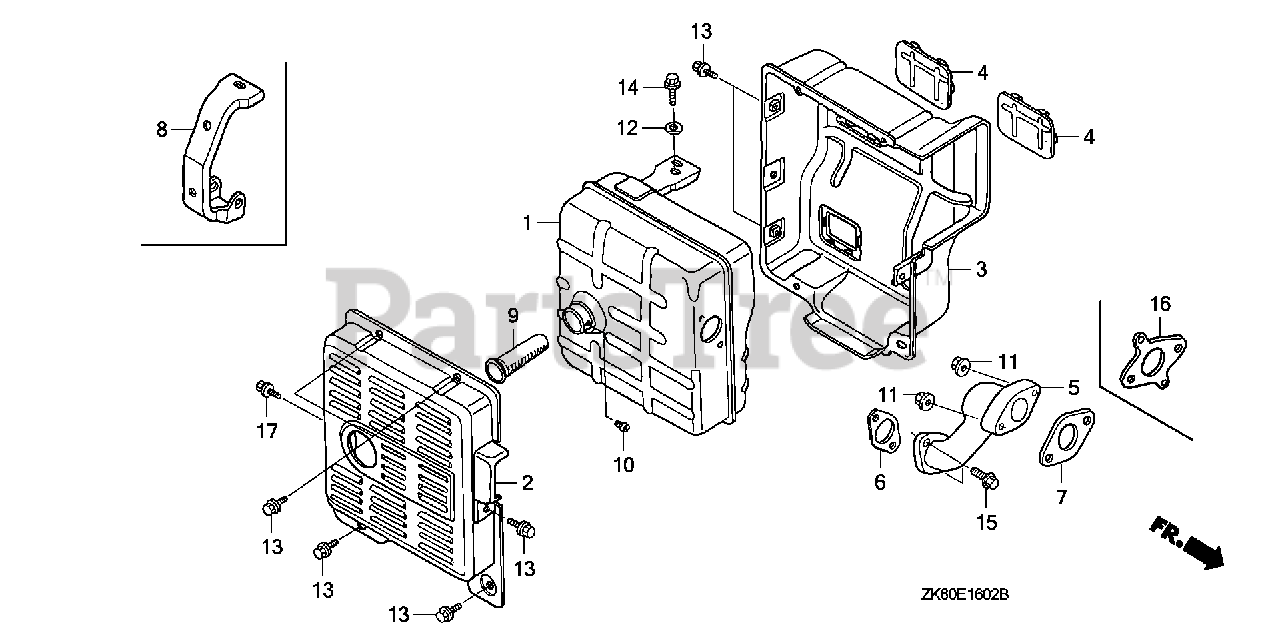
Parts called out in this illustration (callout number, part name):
1	MUFFLER (TSURUMI)
2	PROTECTOR, MUFFLER (OUTER)
3	PROTECTOR, MUFFLER (INNER)
4	SEAL, MUFFLER PROTECTOR
6	GASKET, EX. PIPE
7	GASKET, EX. PIPE
8	STAY A, MUFFLER (TSURUMI)
9	ARRESTER, SPARK
10	SCREW, TAPPING (4X8)
11	NUT, FLANGE (8MM)
13	BOLT, FLANGE (6X12)
15	BOLT, FLANGE (8X20)
17	BOLT, FLANGE (6X12)
